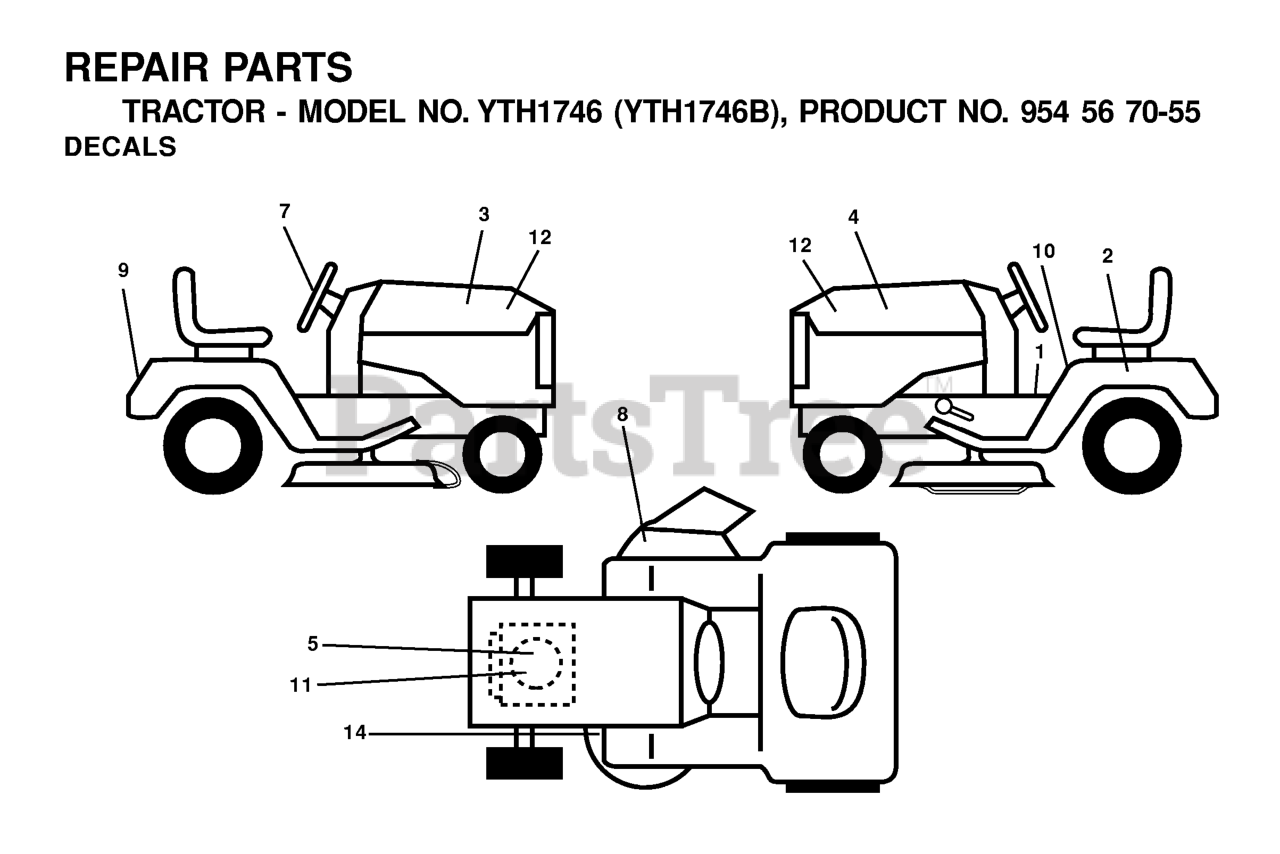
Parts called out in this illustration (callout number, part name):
2	DECAL BTRY SYMBOLS
7	DECAL.WHEEL.STEERING.HUSQ.PERM
8	DECAL.WARN.KEEP.HAND.AWAY
9	DECAL, FENDER
10	DECAL FENDER DANGER
14	DECAL V-BELT SCHEMATIC
